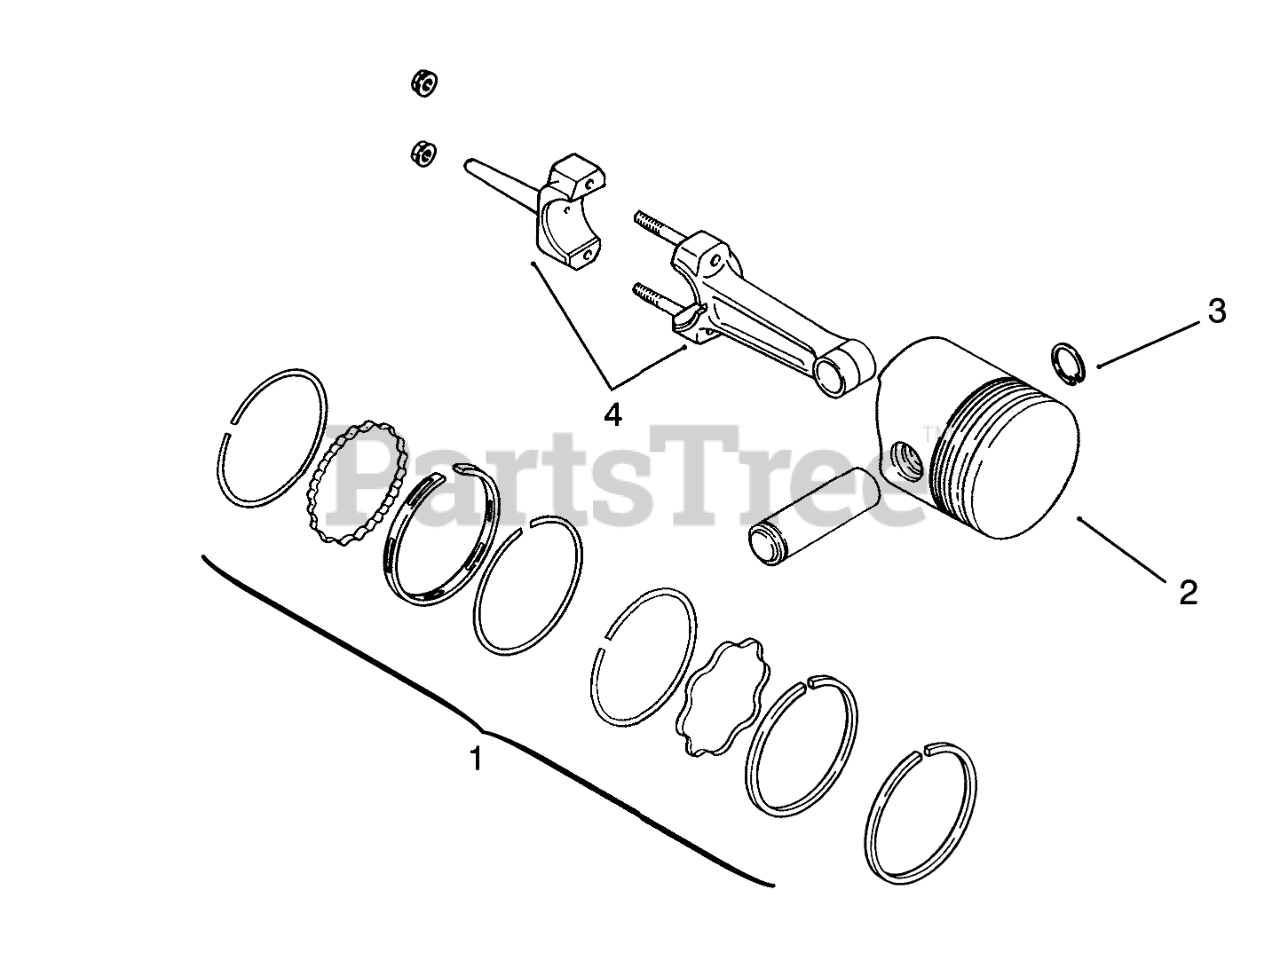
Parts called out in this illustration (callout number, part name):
1	Set-Ring, Std. & .003
2	Piston w/Ring Set Std
3	Piston Pin Retainer
4	Rod-Connecting Std.
